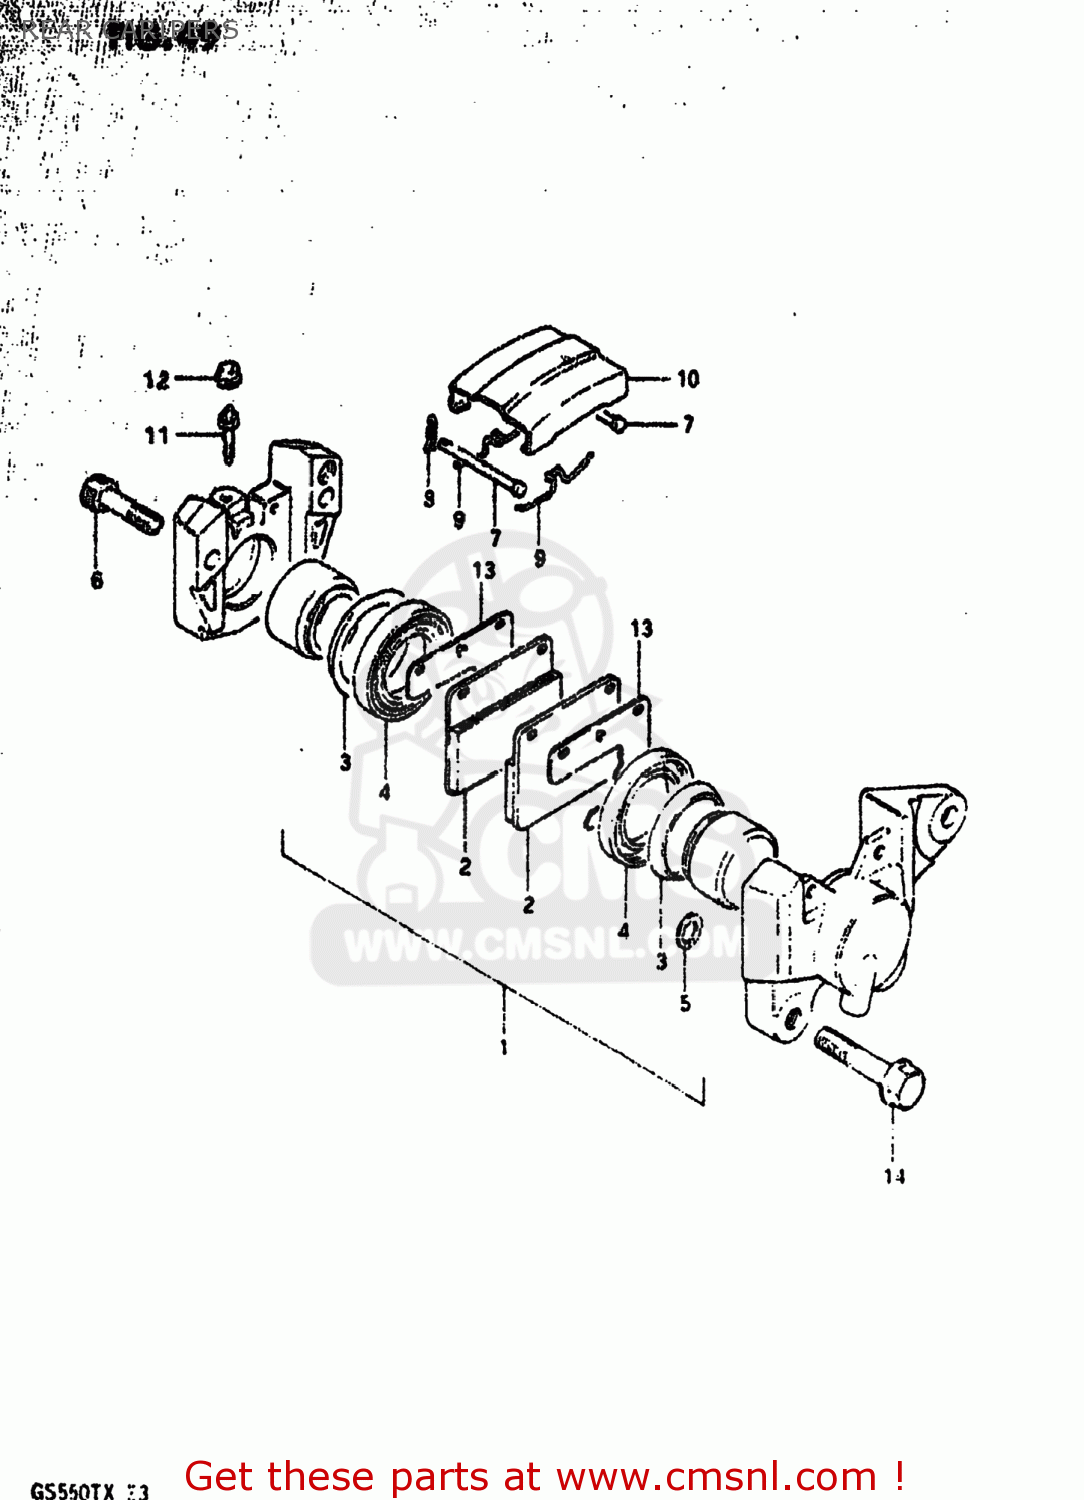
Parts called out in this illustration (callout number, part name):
1	PISTON SET
2	PAD,BRAKE
3	SEAL,PISTON
4	BOOT,PISTON
5	SEAL,JOINT
6	BOLT,CALIPER HOUSING
7	PIN,PAD
8	CLIP,PAD PIN
9	SPRING
10	COVER,DUST
11	BLEEDER
12	CAP,BREATHER
13	SHIM,RR CALIPER
14	BOLT
